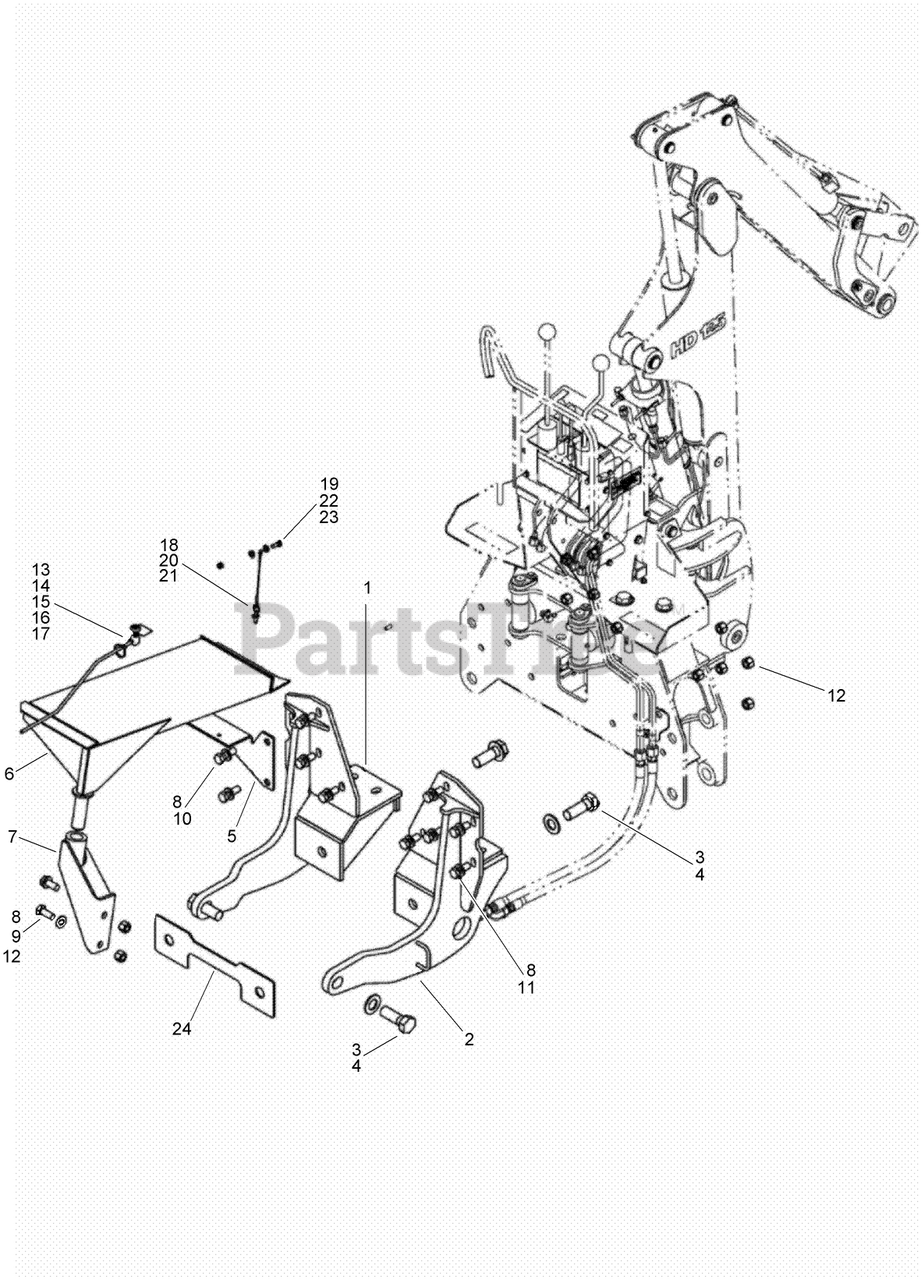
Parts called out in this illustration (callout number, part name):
1	BRACKET-Backhoe Mounting LH
2	BRACKET-Backhoe Mounting RH
5	BRACKET-Walkway Support
6	WALKWAY-backhoe
7	PIVOT-Walkway Mounting
8	WASHER-Flat
9	BOLT-Hex Hd 3/4 x 1-3/4 GR8 ZND
10	SCREW-HH
12	NUT-Prev Trq 3/4 GRC CAD Direct
13	SWITCH-Light
14	DECAL-Backhoe E-Stop
15	KNOB-Fuel Shut-Off
16	HARNESS-Backhoe E-Stop
17	STRAP-TIE
18	WASHER-0.406 x 0.812 x 0.065 in CST ZND
19	WASHER-FLAT
20	PIN-Cotterless
21	RETAINER-ROPE, WIRE
22	SCREW-HH
23	NUT-HEX
24	SHIM-Backhoe to Frame
